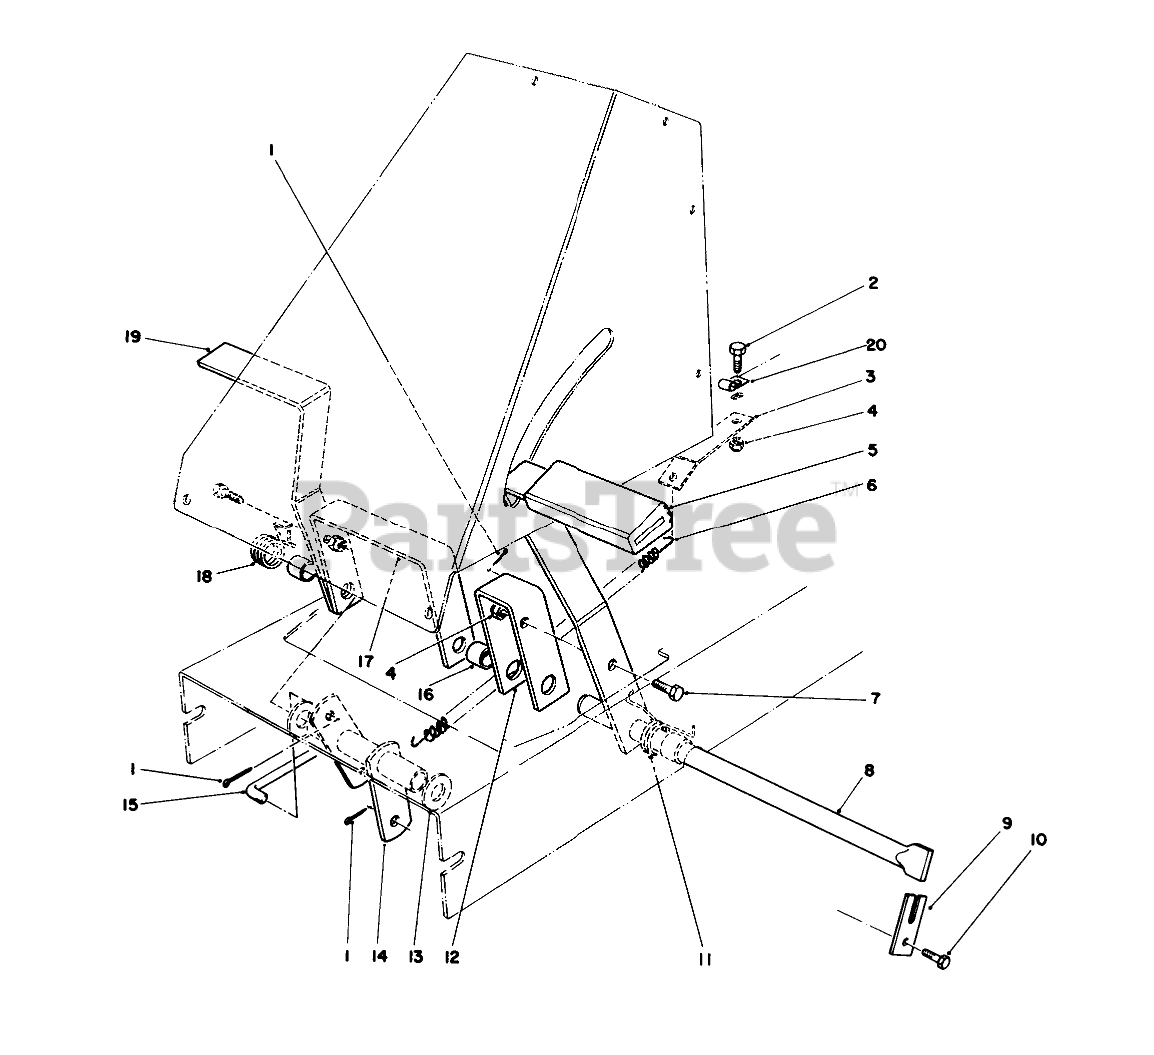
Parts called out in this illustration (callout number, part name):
1	PIN-COTTER
2	SCREW-HH
3	BRKT-SPRING RET
4	NUT-LOCK, NI
5	Pad-Foot Pedal
6	SPRING-EXTENSION
7	SCREW-HH
8	SHAFT-PEDAL PIVOT
9	RETAINER-SHAFT
10	SCREW-HH
11	SPRING-TORS CLUTCH
12	Bracket-Clutch Pedal
13	WASHER-FLAT
14	Pivot Tube
15	ROD-ENGAGE
16	SPACER-PEDAL
17	Bracket-Brake Pedal
18	SPRING-TORS BRAKE
19	Pedal
20	CLAMP
